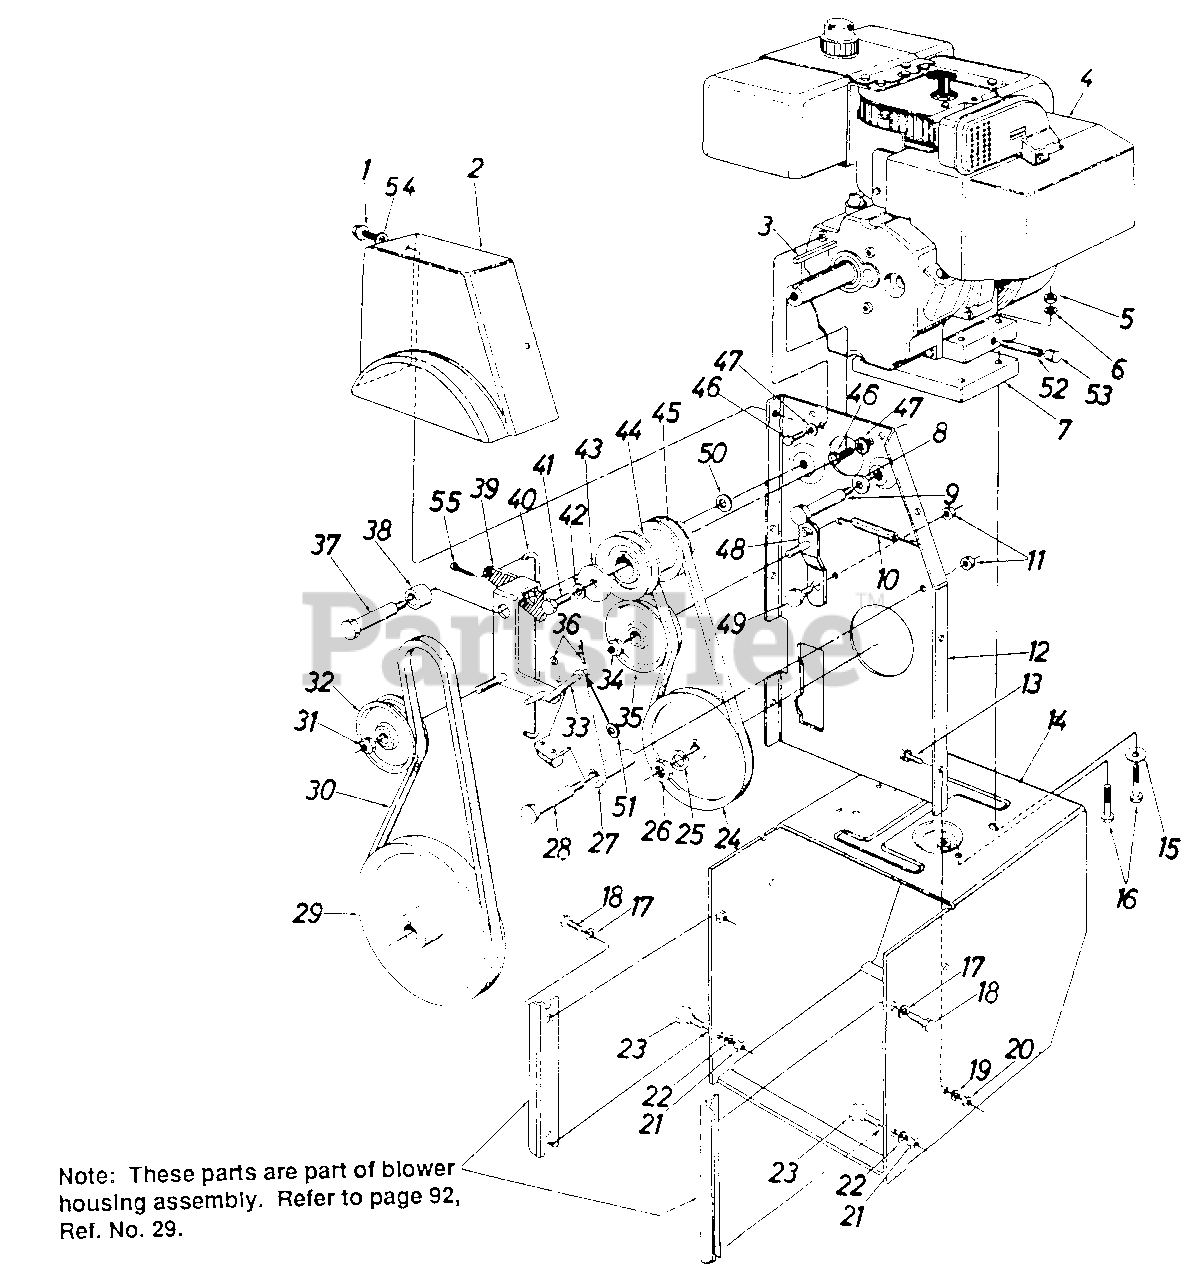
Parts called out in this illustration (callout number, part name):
1	SCREW-HEX HD TAP
2	COVER-BELT
3	KEY-SQ 1/4 X 1.50
5	NUT-HEX 5/16-18
6	WASHER-LOCK-5/16
7	BLOCK-ENGINE SPACER
8	WASHER-BELL .400 ID X .88 X .060
9	SCREW-SHLD .498 DIA X 3.00
10	SPRING-EXTENSION
11	NUT-HEX CENTER L-3/8-16
12	BRACKET ASSY-ENG
13	SCREW-HEX SEMS 5/16-18 X .75
14	FRAME ASSY
15	WASHER-FL-.344 X .62
16	SCREW-HEX
17	WASHER-HDL 3/8
18	SCREW-PILOT 3/8-16 X .88
19	WASHER-LOCK-5/16
20	NUT-HEX 5/16-18
21	NUT-HEX 3/8-16
22	WASHER-HDL 3/8
23	SCREW-SHLD .498 DIA X .340
25	PULLEY 3.00
26	NUT-HEX INS L-5/8-18
27	BRACKET ASSY-BRAKE
28	SCREW-SHLD .498 DIA X 2.005
29	PULLEY-V-1/2 ID X 10.0 OD
30	BELT-V 1/2 X 45
31	NUT-HEX INS L-3/8-24
32	PULLEY-IDLER-FLAT-3.00
33	LINK ASSY-BRAKE
34	NUT-HEX INS L-3/8-24
35	PULLEY-IDLER-FLAT-3.00
36	PIN-COTTER-3/32 DIA X .75
37	SCREW-SHLD .625 DIA X 2.75
41	SCREW 3/8-24 X 1.25 GR5
42	WASHER-HDL 3/8
43	WASHER-FL
44	PULLEY-ENGINE
45	BELT-3V-35.5
46	SCREW-HEX 5/16-24 X .62
47	WASHER-BELL .337 X .867 X .057
48	BRACKET ASSY-DR IDLER
49	SCREW-SHLD .625 DIA X .163
50	WASHER-BELL .3/8ID X 1.12OD X .030
51	WASHER-FL-.385 ID X .62 OD X .033
52	NIPPLE-PIPE
53	CAP-HEX PIPE THD
54	WASHER-FL-.344 X .62
55	PIN-INTERN COT-5/16 DIA
